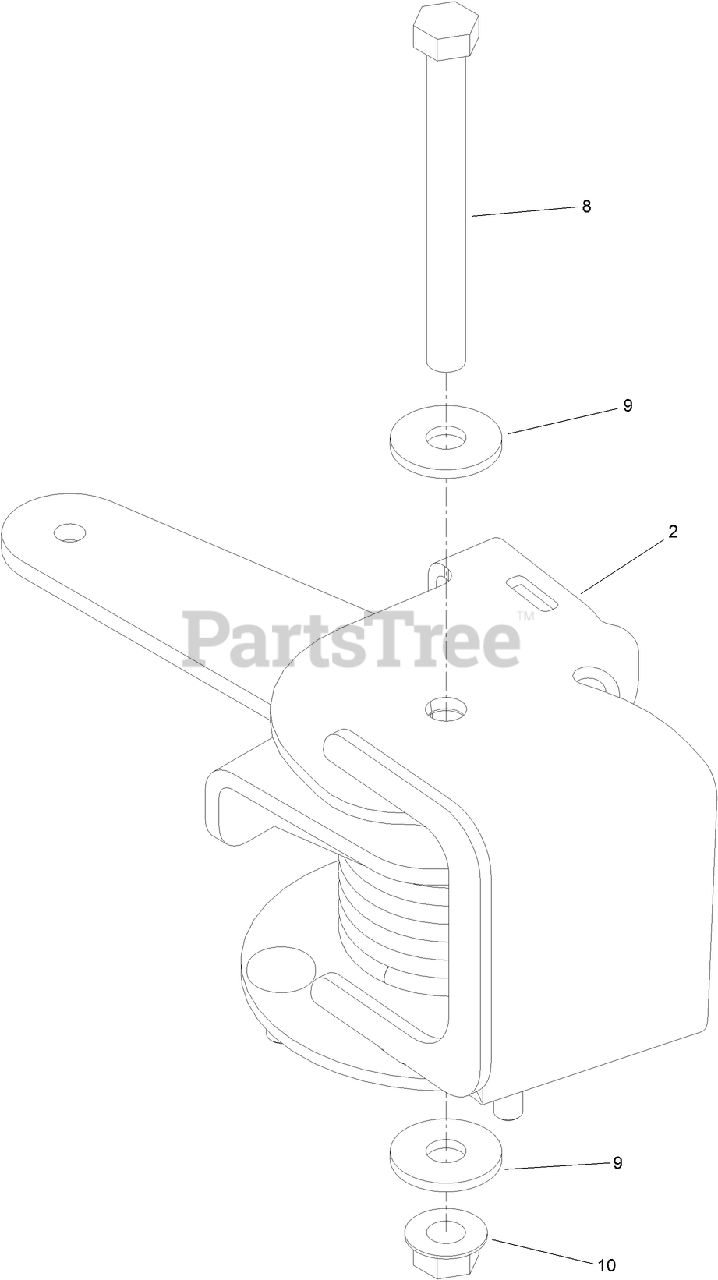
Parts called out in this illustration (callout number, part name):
2	PIVOT-IDLER
8	SCREW-HH
9	WASHER-SUPPORT
10	NUT-HF
